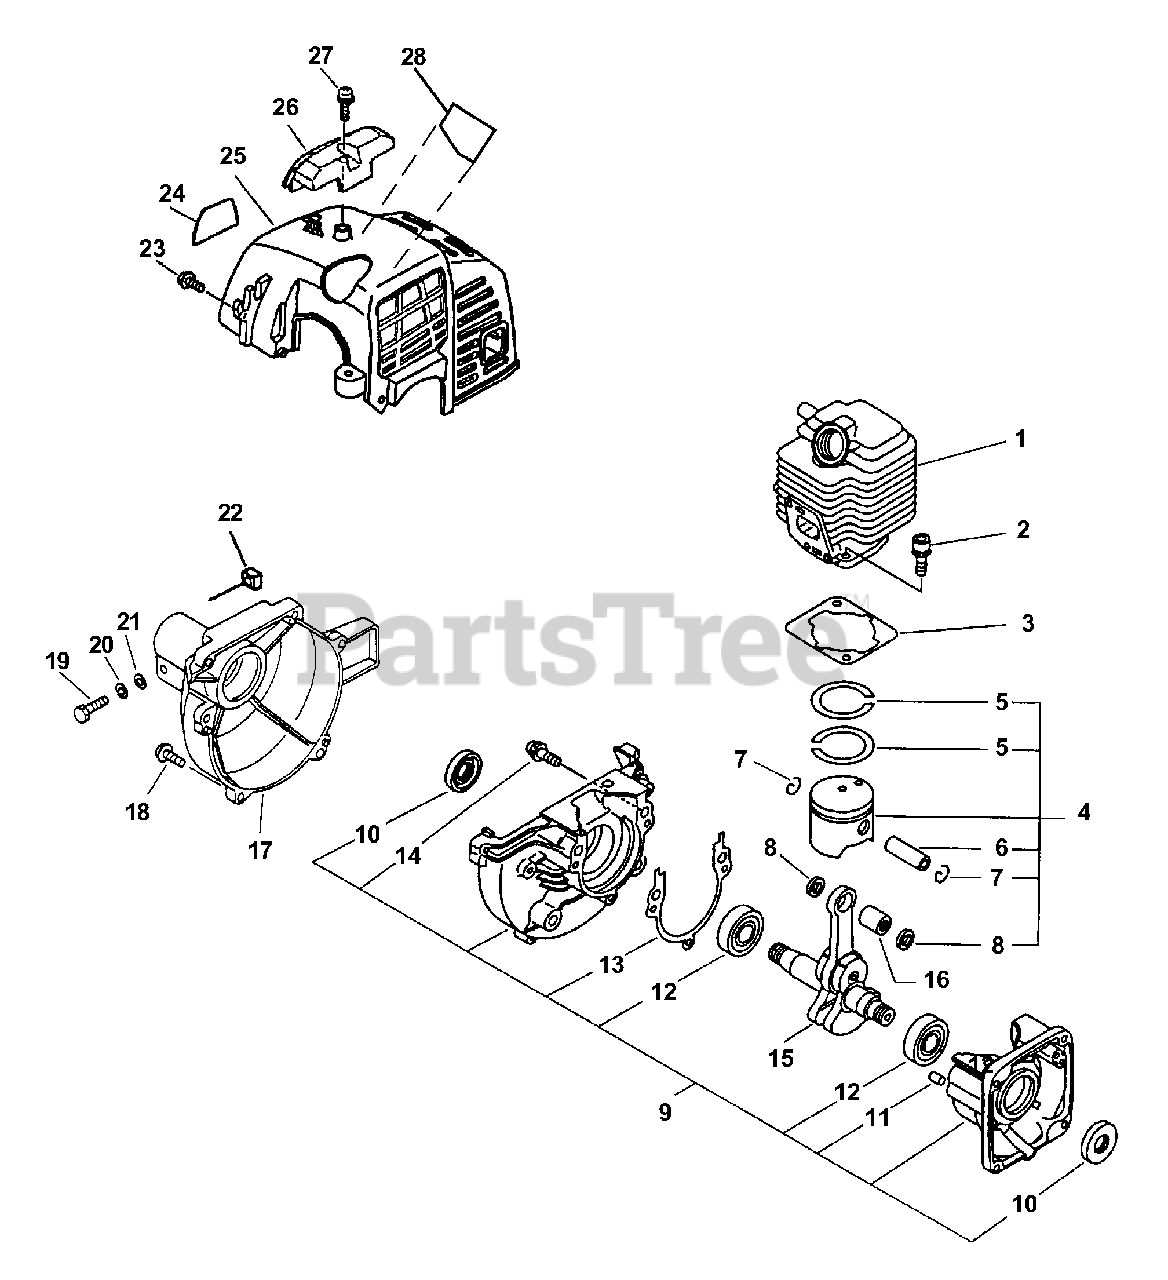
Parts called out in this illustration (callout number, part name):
1	CYLINDER
2	BOLT 5×22
3	GASKET, CYLINDER
4	PISTON KIT
5	RING, PISTON
6	PIN, PISTON 8
7	RING, SNAP
8	WASHER, THRUST
9	CRANKCASE ASSY
10	SEAL, OIL 12
11	PIN, LOCATING 4
12	BEARING, BALL - 6201 C3
13	GASKET, CRANKCASE
14	BOLT 5×28
15	CRANKSHAFT ASSY
16	BEARING, NEEDLE
17	COVER, FAN
18	BOLT 4×18
19	BOLT 5×28
20	WASHER, SPRING 5
21	WASHER, FLAT 5.5×10×0.8
22	NUT - 5 -- SQUARE
23	SCREW 4×12
24	LABEL, MODEL
25	COVER, ENGINE - ORANGE
26	GUARD, TOP - BLACK
27	SCREW 5×16
28	LABEL, CAUTION
